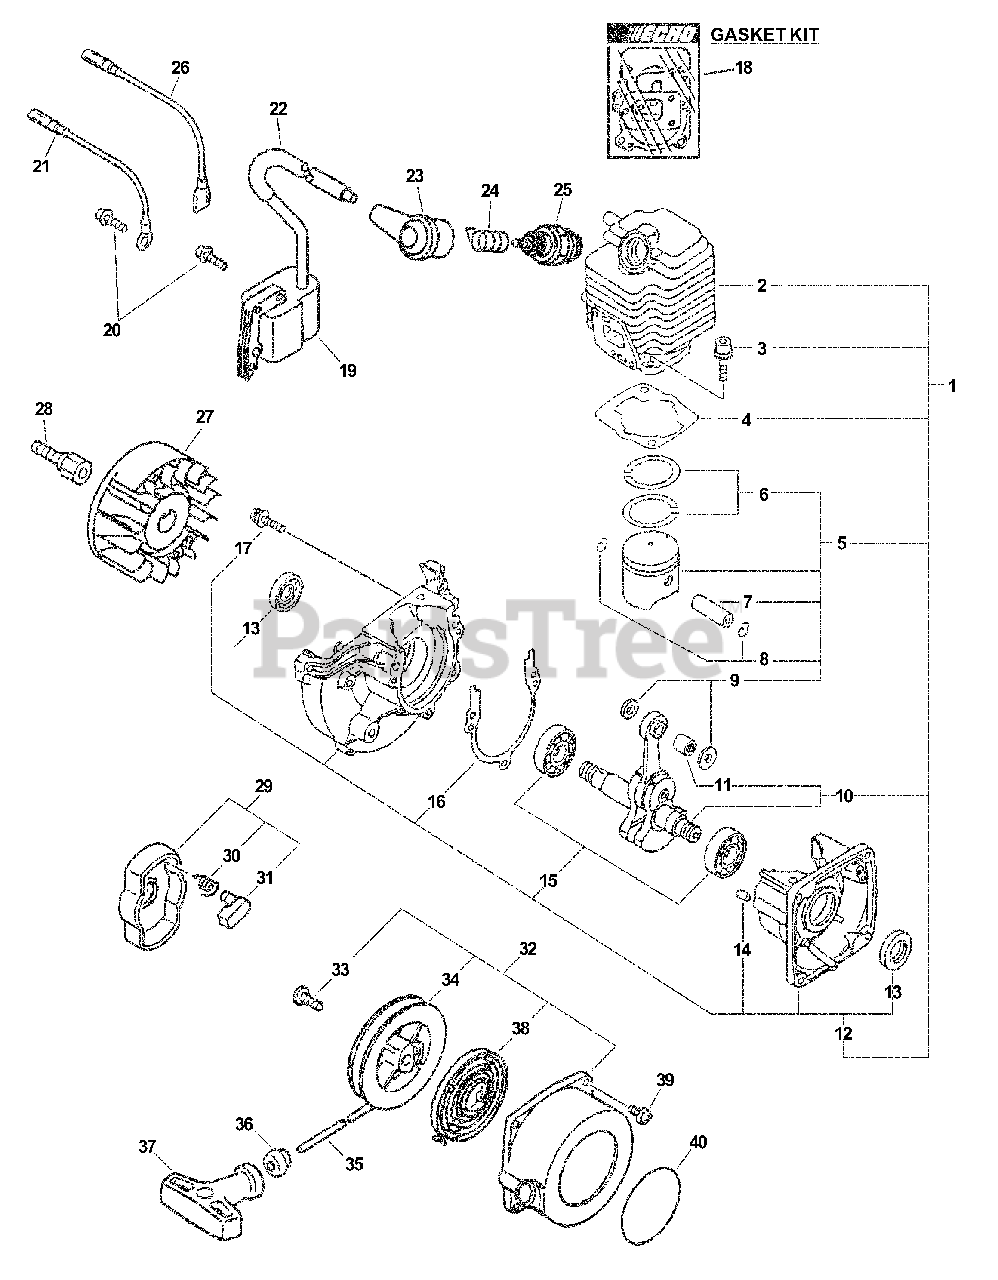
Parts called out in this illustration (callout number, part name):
1	SHORT BLOCK -- SB1049
2	CYLINDER
3	SCREW - 5X22
4	GASKET, CYLINDER
5	PISTON KIT
6	RING, PISTON
7	PIN, PISTON
8	RING, RETAINING
9	SPACER, PISTON
10	CRANKSHAFT ASSY
11	BEARING, NEEDLE
12	CRANKCASE KIT
13	SEAL, OIL
14	PIN - LOCATING
15	BEARING, BALL - 6201
16	GASKET, CRANKCASE
17	SCREW - 5X28
18	GASKET KIT
19	COIL, IGNITION
20	SCREW - 4X22
21	LEAD - GROUND
23	CAP, SPARK PLUG
24	TERMINAL, SPARK PLUG CAP
25	SPARK PLUG -- BPM-7Y
26	LEAD - IGNITION
27	FLYWHEEL
28	HUB, FAN
29	STARTER PAWL ASSY
30	SPRING, RETURN
31	PAWL, STARTER - BLACK
32	STARTER ASSY
34	REEL, ROPE
35	ROPE, STARTER - 3X1000
36	GUIDE, ROPE
37	GRIP, STARTER
38	SPRING, REWIND
39	SCREW - 4X16
40	LABEL - ECHO
